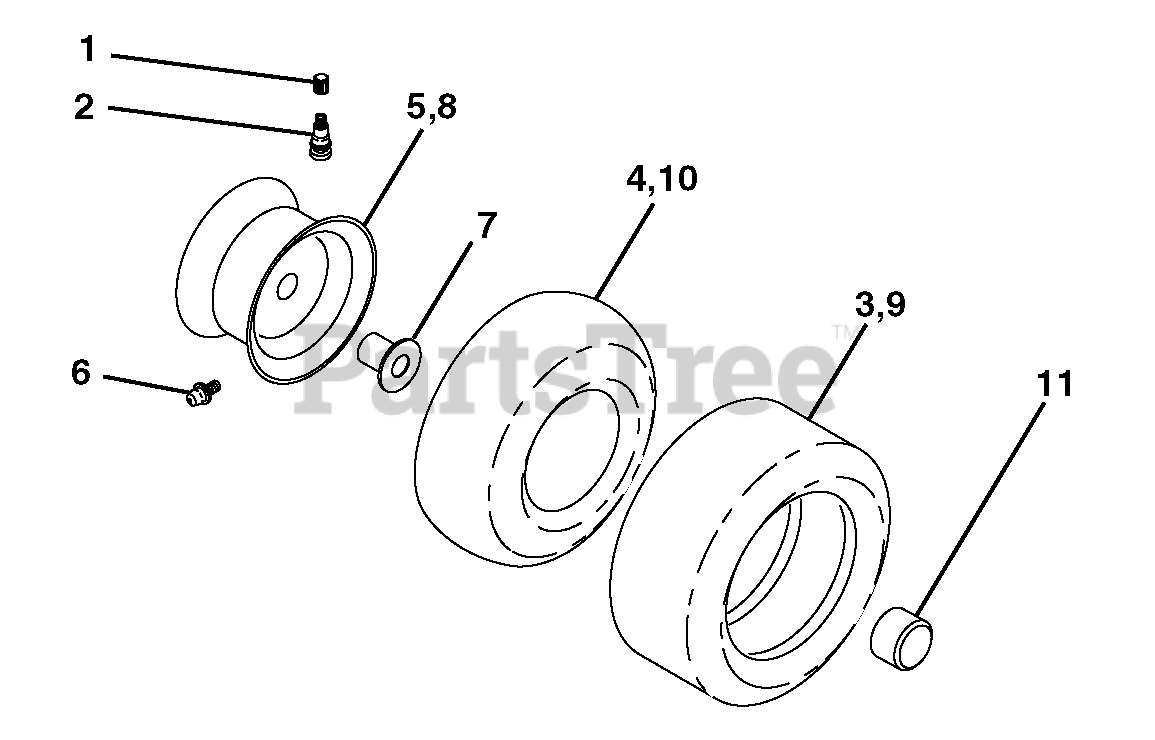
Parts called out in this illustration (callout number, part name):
1	Cap Valve Tire
2	Stem Valve
3	Tire F T 15 x 6 0 - 6 Service
4	Tube Front
5	Rim Asm 6" front Service
6	Fitting Grease
7	Bearing Flange
8	Rim Asm 8" rear Service
9	Tire R T 20 x 8-8 Service
10	Tube Rear
11	Cap Axle Blk 1 50 x 1 00
11	Sealant, Tire ( 10 oz. Tube)
